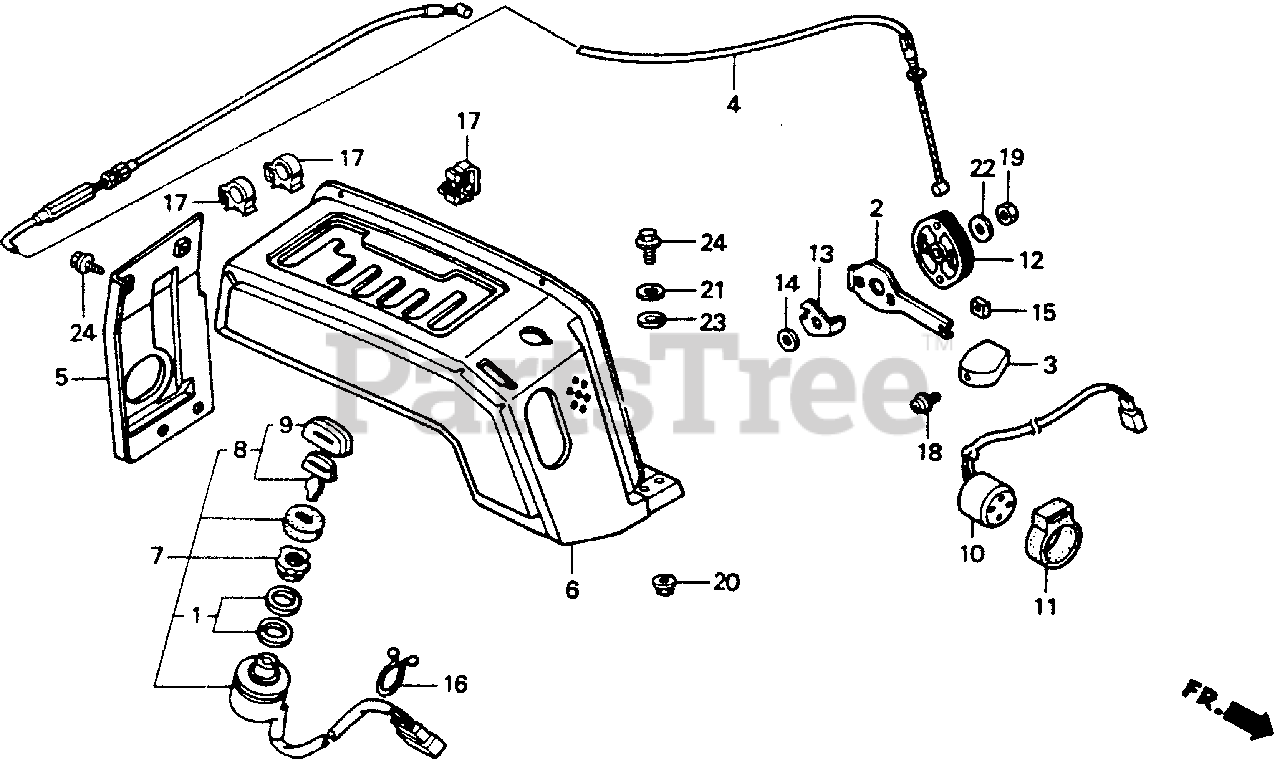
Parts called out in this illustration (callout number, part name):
1	WASHER SET, COMBINATION SWITCH
2	LEVER, THROTTLE
3	KNOB, THROTTLE LEVER *NH105* (MAT BLACK)
4	CABLE, THROTTLE (NOT AVAILABLE)
5	STAY, CHANGE GUIDE
6	GUIDE, CHANGE LEVER (NOT AVAILABLE)
7	SWITCH ASSY., COMBINATION
8	KEY ASSY., COMBINATION SWITCH
10	BUZZER, WARNING
11	SUSPENSION, AUDIBLE PILOT
12	REEL, CABLE
13	STOPPER, REEL
14	WASHER (11MM)
15	NUT, SQUARE (4MM)
16	CLIP, PURSE LOCK
17	CLIP, WIRE HARNESS (13MM) (GRAY)
18	SCREW-WASHER (4X8)
19	NUT, HEX. (6MM)
20	NUT, FLANGE (6MM)
21	WASHER, PLAIN (6MM)
22	WASHER, PLAIN (6MM)
23	WASHER, SPRING (6MM)
24	BOLT, FLANGE (6X16)
